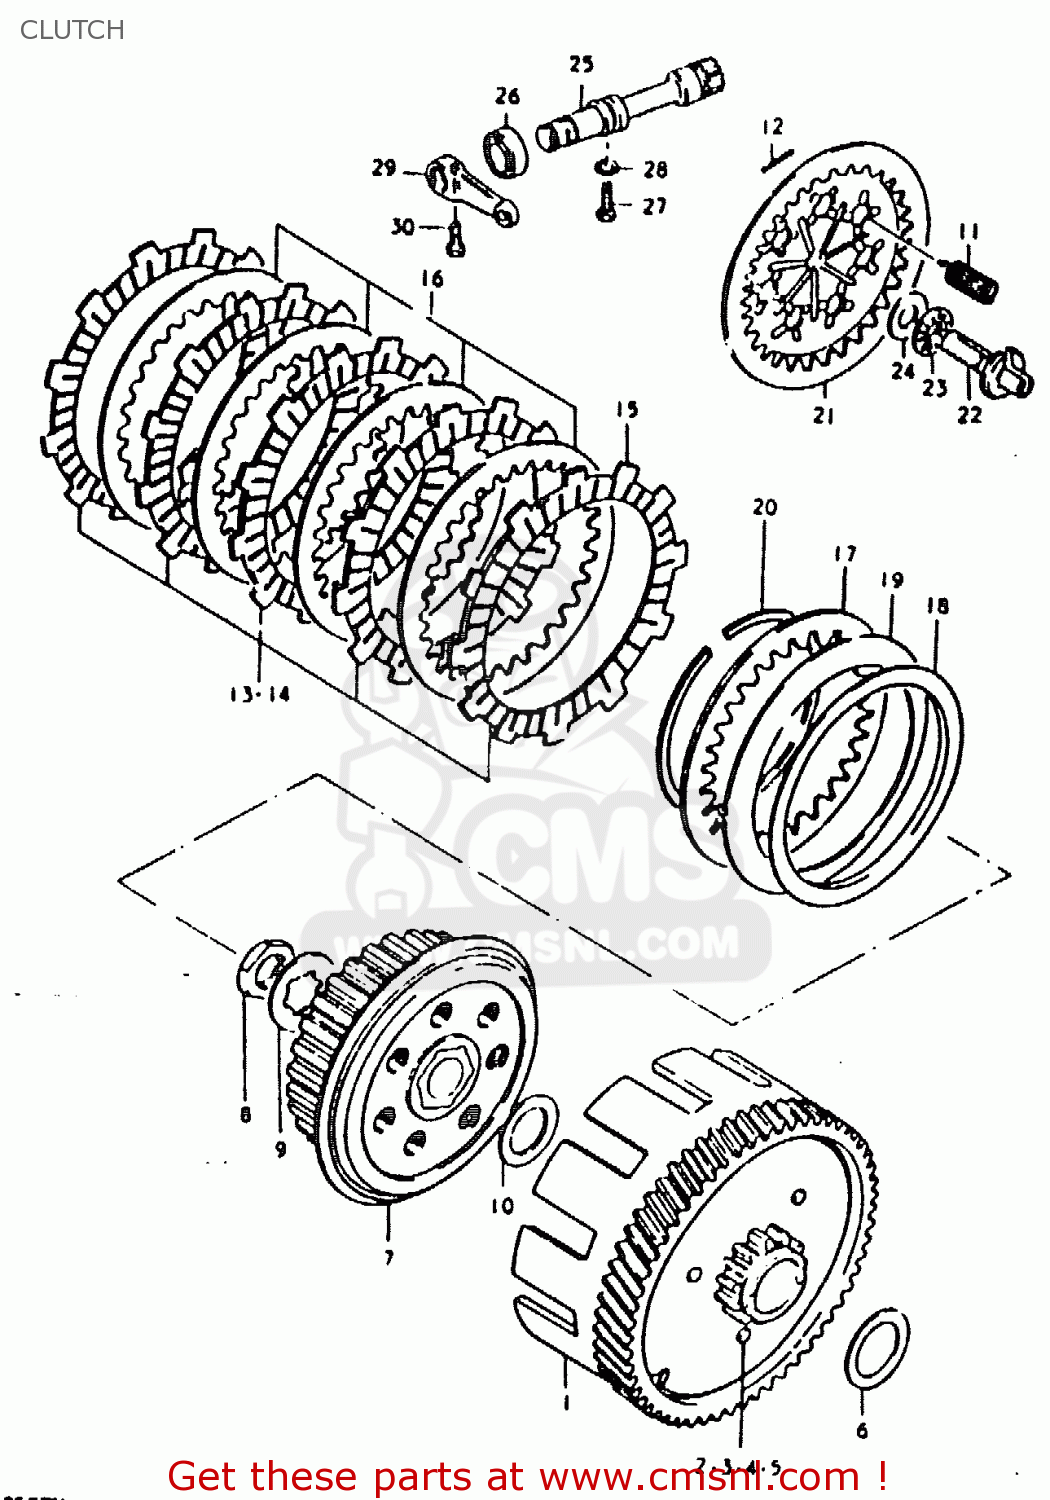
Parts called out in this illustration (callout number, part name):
1	GEAR ASSEMBLY,PRIMARY DRIVE
2	DAMPER,PRIMARY DRIVEN
3	DAMPER,PRI DRIVEN GEAR NO.2
4	PLATE
5	RIVET
6	WASHER
7	HUB,CLUTCH SLEEVE
8	NUT
9	WASHER,LOCK
10	WASHER
11	SPRING
12	PIN(2.5X19.8)
13	PLATE,CLUTCH DRIVE
14	PLATE,CLUTCH DRIVE
15	PLATE,CLUTCH DRIVE (MCA)
16	PLATE,CLUTCH DRIVEN (NAS)
17	PLATE,CLUTCH DRIVEN(T:2.0) (NAS)
18	SEAT,WAVE WASHER
19	WASHER
20	CIRCLIP
21	PLATE,CLUTCH PRESSURE
22	BACK,CLUTCH RELEASE
23	BEARING(10X22X2.8)
24	WASHER(10.1X21.4X0.8)
25	PINION,CLUTCH RELEASE
26	OIL SEAL
27	BOLT(6X12)
28	WASHER
29	ARM,CLUTCH RELEASE
30	BOLT
